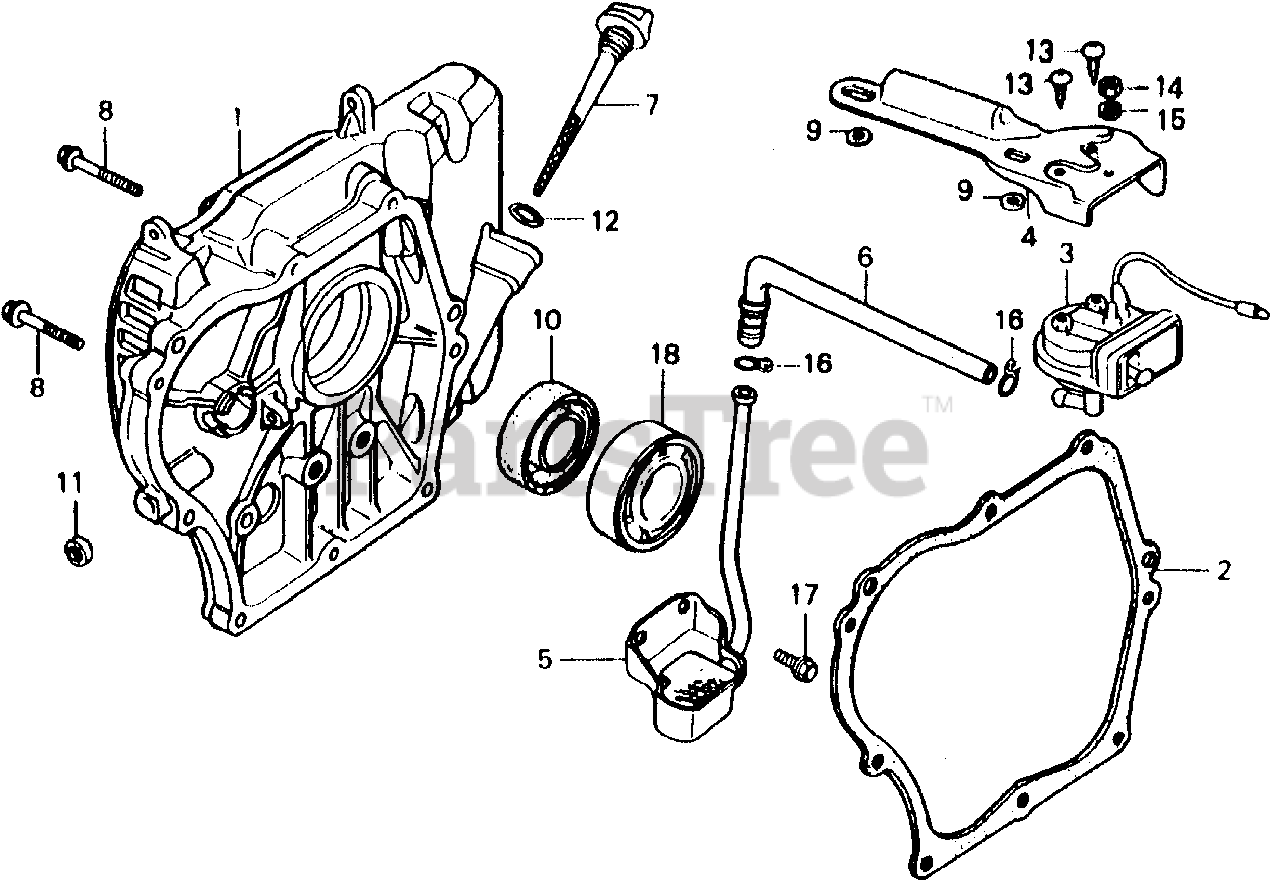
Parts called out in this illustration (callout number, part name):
1	COVER ASSY., CRANKCASE
2	GASKET, COVER
3	SWITCH ASSY.
4	BRACKET, UNIT SWITCH
6	TUBE, OIL ALERT
7	CAP, OIL FILLER
8	BOLT, FLANGE (6X32)
9	WASHER (18MM)
10	OIL SEAL (25X41X6)
11	OIL SEAL (8X14X5)
12	O-RING (16MM)
13	SCREW, TAPPING (5X10)
14	NUT, HEX. (5MM)
15	WASHER, SPRING (5MM)
16	CLIP, TUBE (C11)
17	BOLT, FLANGE (6X12)
18	BEARING, RADIAL BALL (6205)
